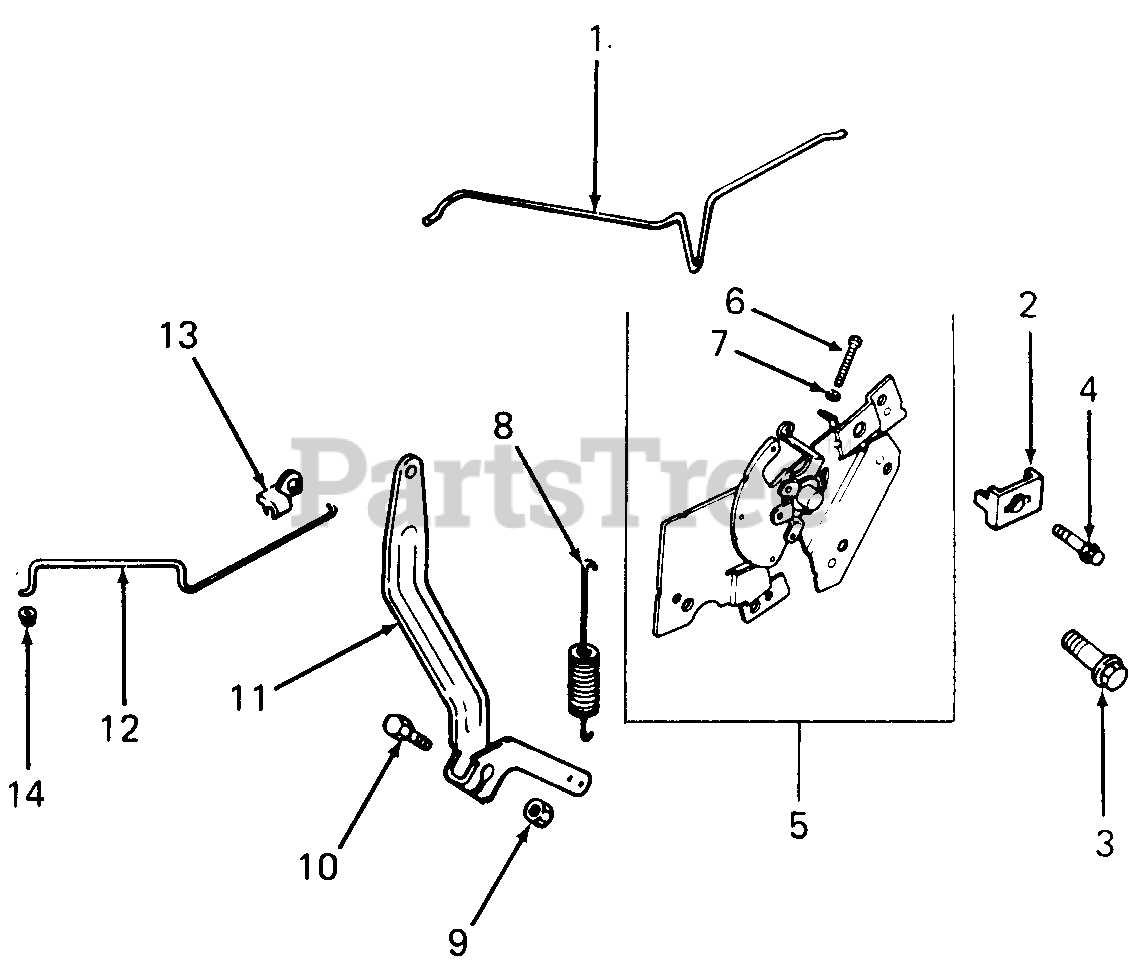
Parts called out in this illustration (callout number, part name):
1	Linkage, Choke
2	Clamp, Cable
3	Screw, Speed Control Bracket, M6 X 1.0 X 20
4	Screw, Cable Clamp, M5 X 0.8 X 16
5	Control, Speed Assy
6	Screw, RMP Adj
7	Nut
8	Spring, Governor
9	Nut, Governor Arm, M6 X 1.0
10	Screw, Governor Arm, M6 X 1.0 X 25
11	Lever, Governor
12	Linkage, Throttle
13	Bushing, Black, Linkage Retaining
14	Bushing, Natural Linkage Retaining
